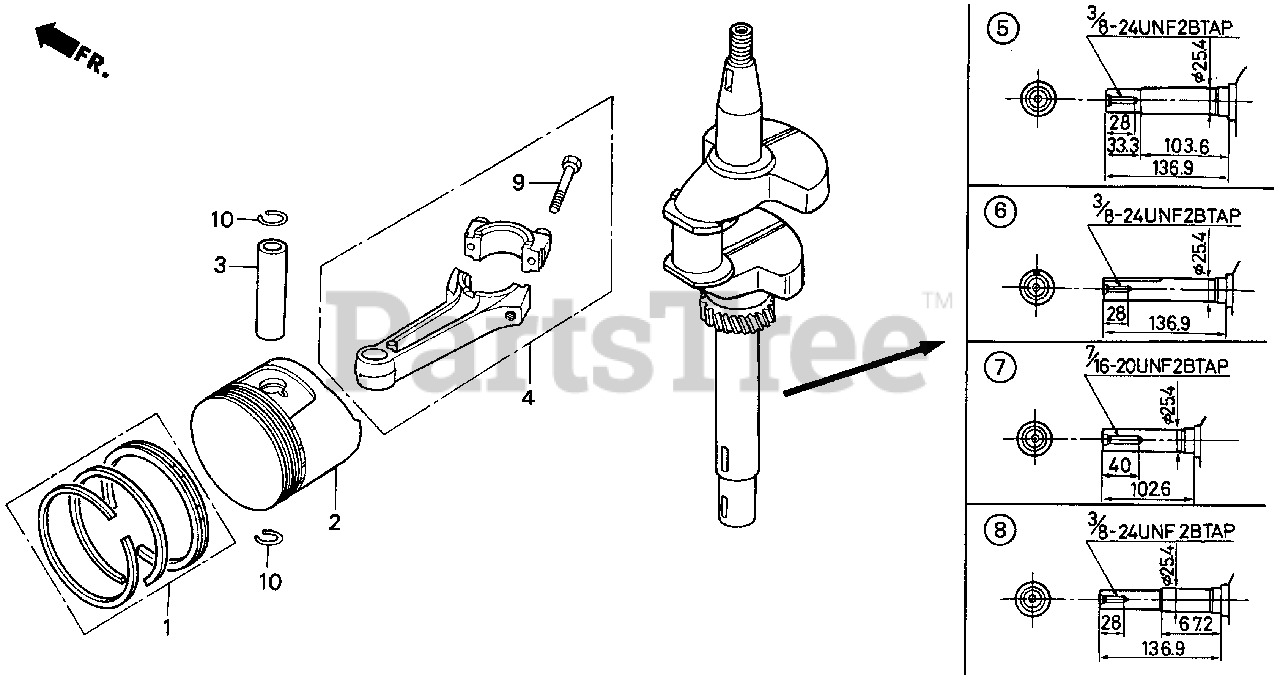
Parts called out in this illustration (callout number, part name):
1	RING SET, PISTON (STD)
1	RING SET, PISTON (OS 0.25)
1	RING SET, PISTON (OS 0.50)
1	RING SET, PISTON (0.75)
2	PISTON (STD)
2	PISTON (OS 0.25)
2	PISTON (OS 0.50)
2	PISTON (0.75)
3	PIN, PISTON
4	ROD ASSY., CONNECTING
4	ROD ASSY., CONNECTING (US 0.25)
5	CRANKSHAFT (N1 TYPE)
9	BOLT, CONNECTING ROD
10	CLIP, PISTON PIN (18MM)
